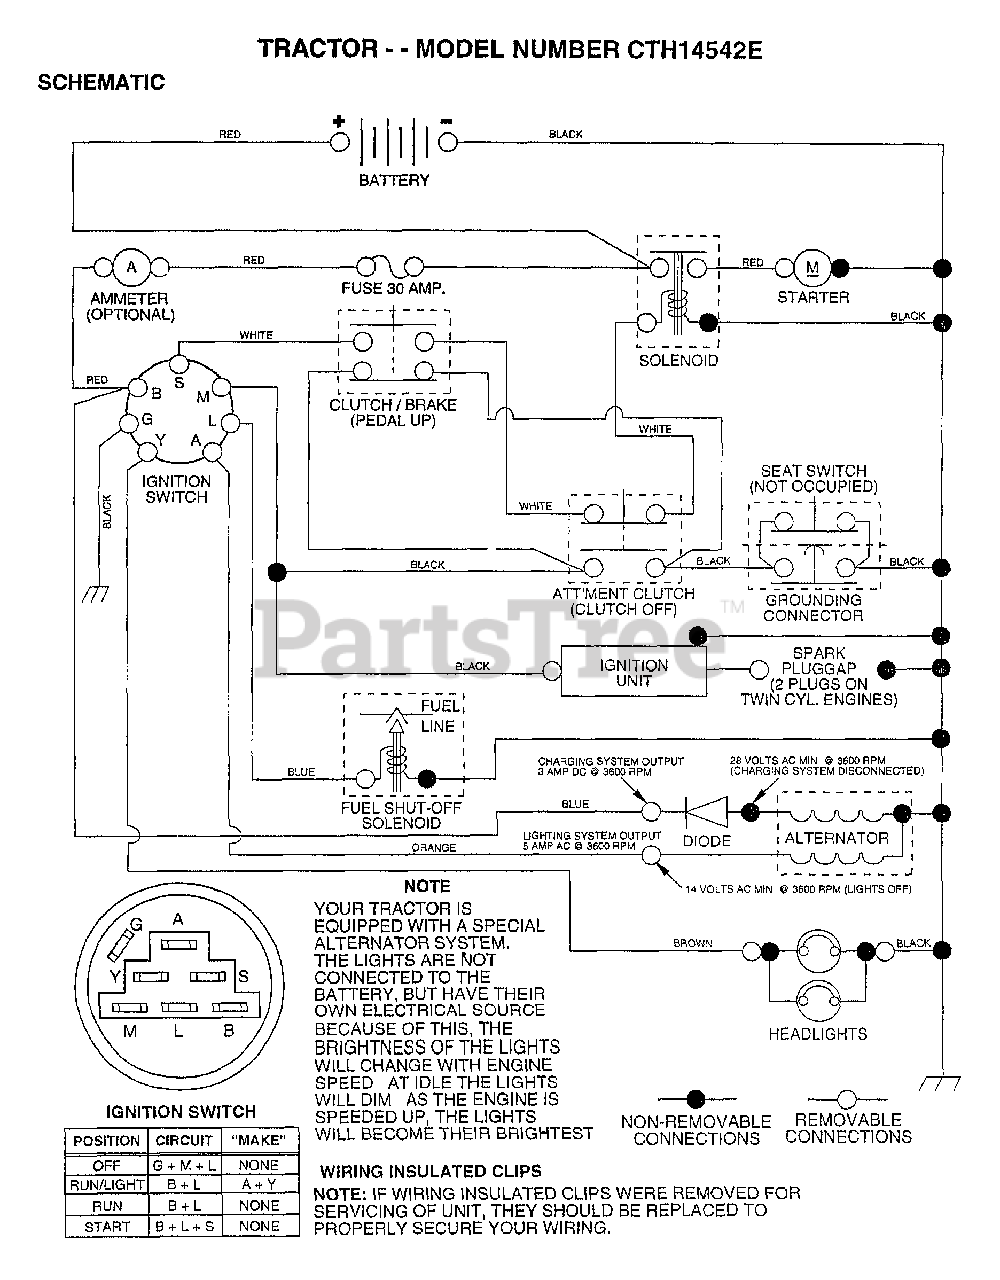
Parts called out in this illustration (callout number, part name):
2	BOLT LT
3	WASHER
4	LOCKWASHER
7	TUBE T
8	"CASE,BATTERY.MECH"
9	HOSE CLAMP T
15	FASTNER.SNAP-IN
16	SWITCH INTERLOCK
20	NUT
21	"HARNESS,LIGHT SOC"
22	HEADLAMP BULB
24	CABLE.BTRY.6GA.38
25	CABLE.BTRY.6GA.RD
26	FUSE HYT
28	CABLE T
29	SWITCH SEAT
30	SWITCH IGN 4POS
31	NUT IGNITION
32	COVER KEY SWITCH
33	KEY
40	HARNESS IGNITION
41	BOLT HXHD FIN
44	NUT HXKEP 1/4X20
48	ADAPTER AMMETER
70	HARNESS.ENG.DUAL
